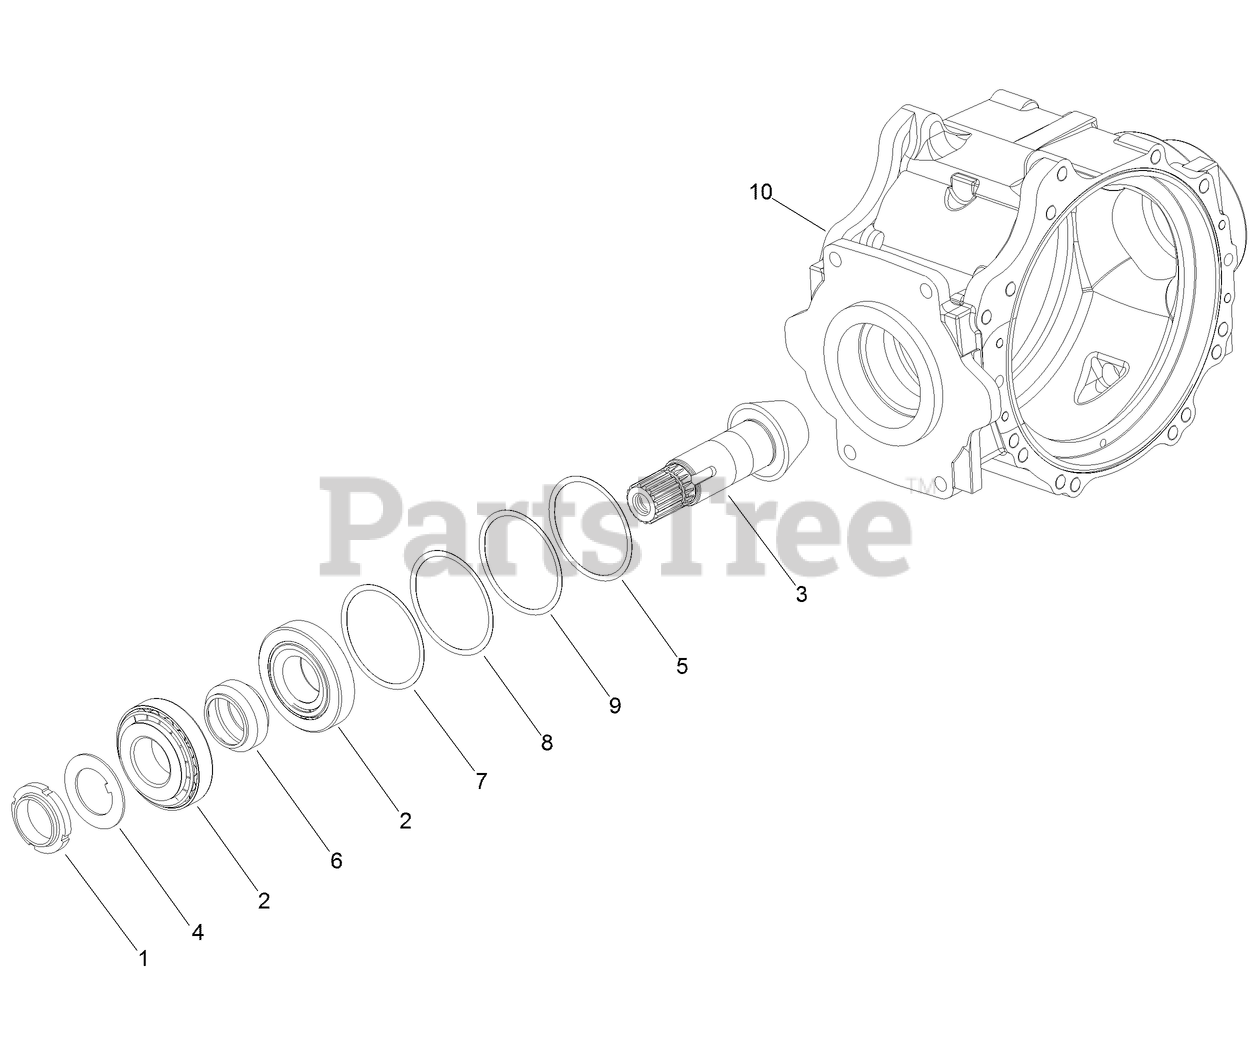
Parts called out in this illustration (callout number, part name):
1	NUT-LOCK
2	BEARING-ROLLER, TAPER
3	PINION-BEVEL
4	WASHER-ROTATION, ANTI
5	SHIM (0.5)
6	SPACER-DEFORMABLE
7	SHIM (0.35)
8	SHIM (0.3)
9	SHIM (0.4)
10	HOUSING-CENTRAL
